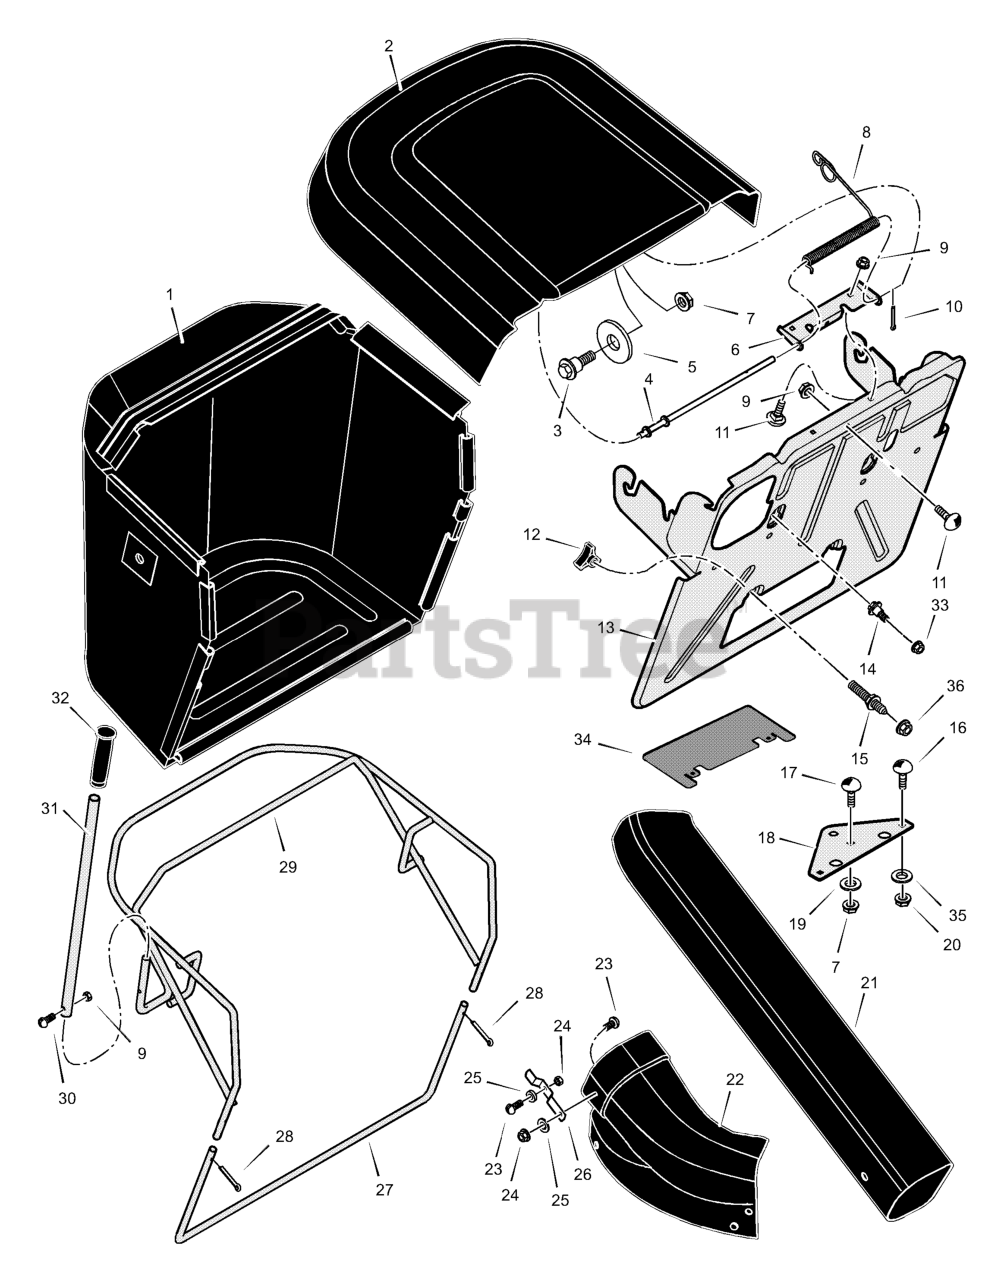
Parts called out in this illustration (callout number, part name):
1	Bag, Cloth
2	Cover, Bag (Black)
3	Bolt, Shoulder
4	Rod, Bag Lid
6	Hinge, Bag Top
7	Nut
8	Spring, Torsion
10	Pin, Cotter
11	Bolt, Carriage
13	Assembly, Bag Plate & Hanger
14	Bolt, Shoulder
15	Stud, Double End
16	Bolt, Carriage
17	Bolt, Carriage
18	Bracket, Hitch Extension
19	Washer
20	Nut
21	Tube, Connecting
22	Tube, Extension
24	Acorn Nut
26	Spring, Leaf
27	Tube, Bag Frame
28	Pin, Cotter
31	Lever, Dump
33	Nut, Flange
34	Baffle, Bag Plate
35	Washer
36	Nut
